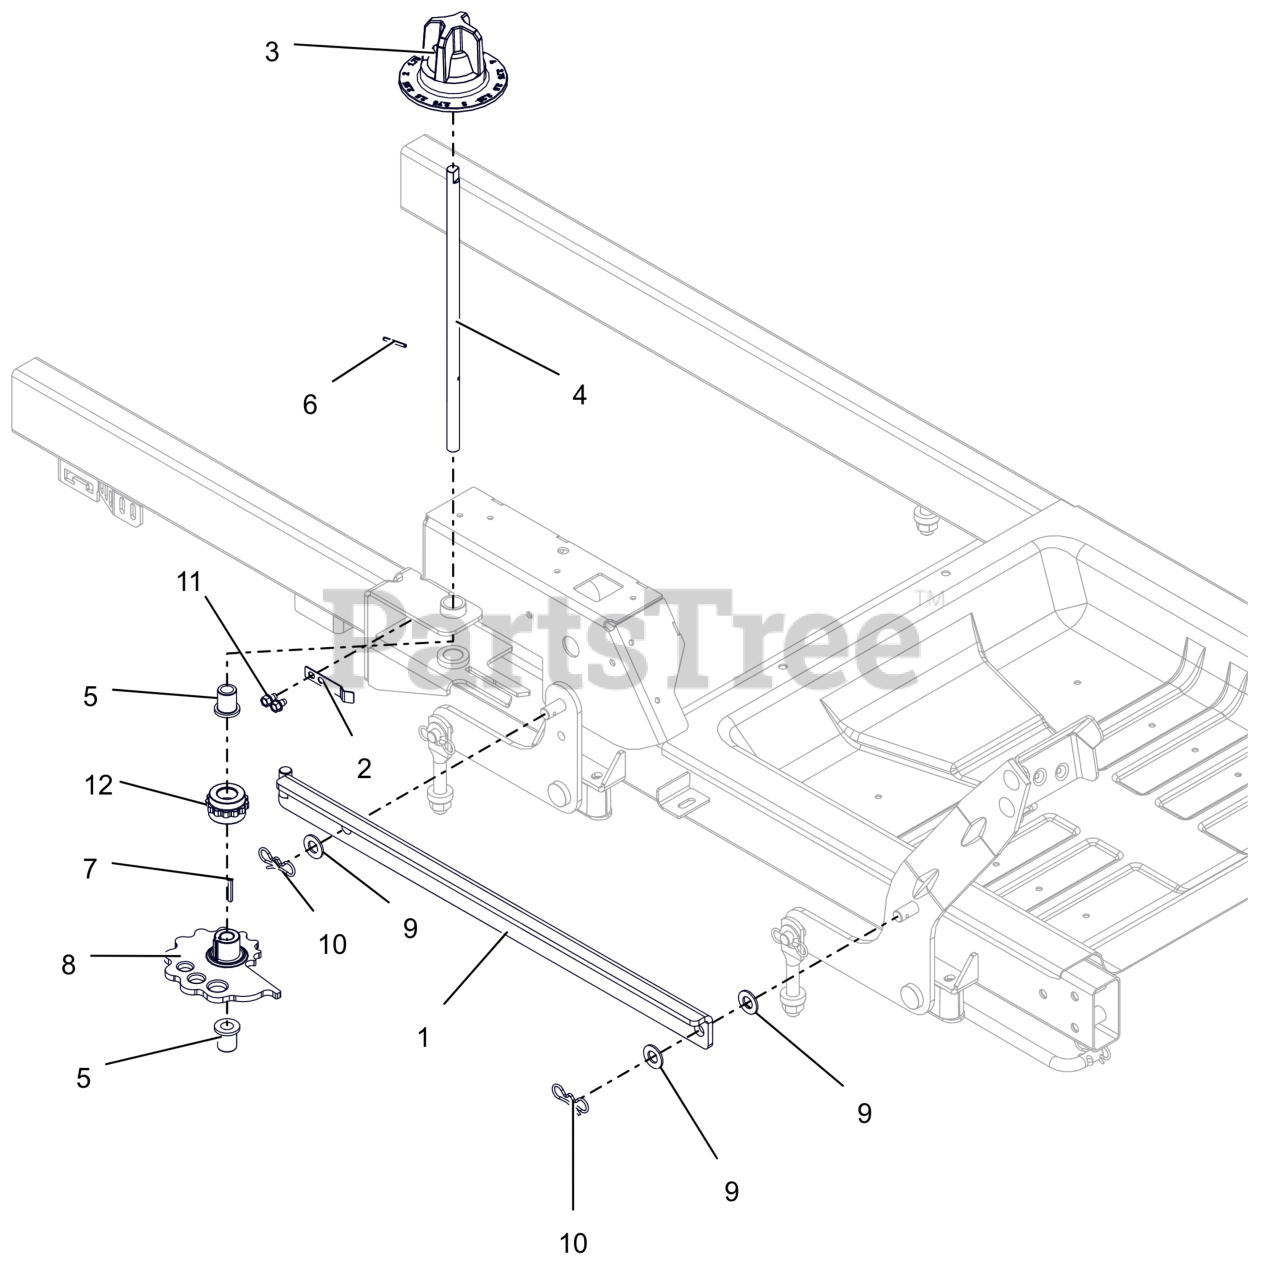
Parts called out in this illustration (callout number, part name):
1	WLDMT, HOC LINK
2	ARM, HOC DETENT
3	KNOB, HOC DIAL
4	SHAFT, HOC CAM
5	BSHG-FLG, .503X.750X.875X1.00
6	PIN-ROLL .125X1.00
7	KEY, 1/8 X 1/8 X 1.0
8	CAM, HOC (PM)
9	WSHR-FL-NYL .518X1.000X.080
10	PIN, BOWTIE .091X1.875 ZCC
11	SCR,TAP .25-20X.375 HWH TR ZCC
12	GEAR, HOC INDEX
